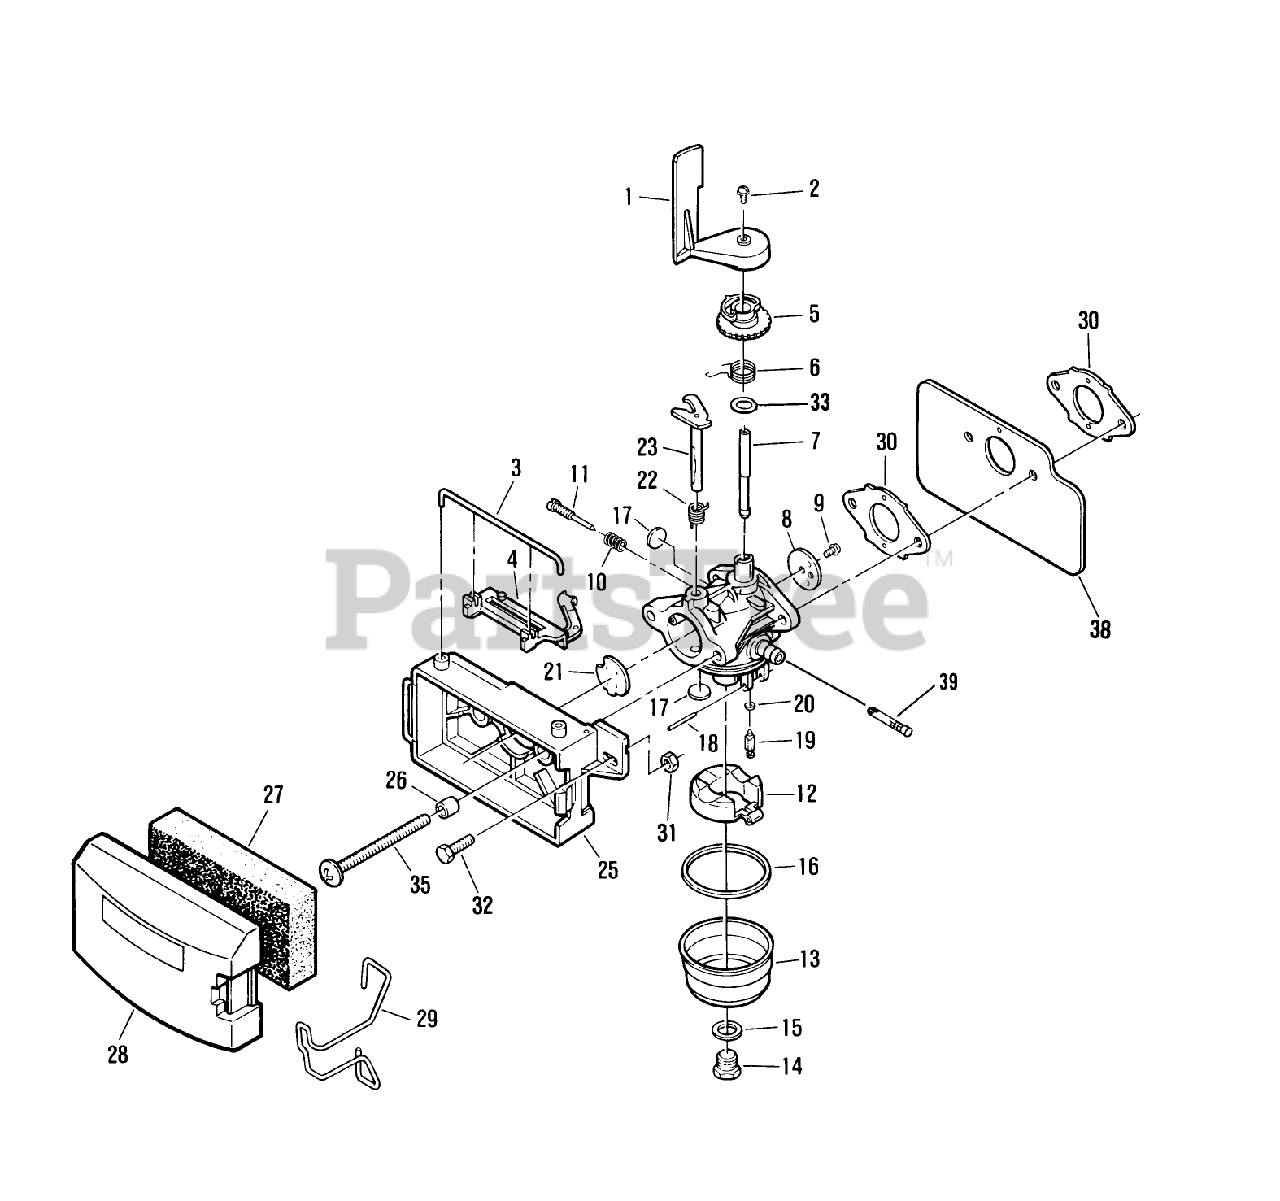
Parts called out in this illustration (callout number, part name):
1	AIR VANE F
2	SCREW F
3	RETAINER
5	COLLAR A/VAVE F
6	THROTTLE SPR E
7	Shaft-Throttle
8	Valve-Throttle
9	Screw-Throttle Valve
10	Spring-Idle Needle
11	Needle-Idle
13	Bowl-Fuel
14	Screw-Bowl Retainer
15	Gasket-Bowl Retainer
16	Gasket-Fuel Bowl
17	Plug-Welch
18	Shaft-Float
19	Valve-Inlet Needle
20	Seat-Valve
21	Valve-Choke
22	Spring-Choke Return
23	Shaft-Choke
29	RETAINER-COVER, FILTER
30	GASKET CARB S
33	WASHER VF
39	SCREEN FUEL PITTS
